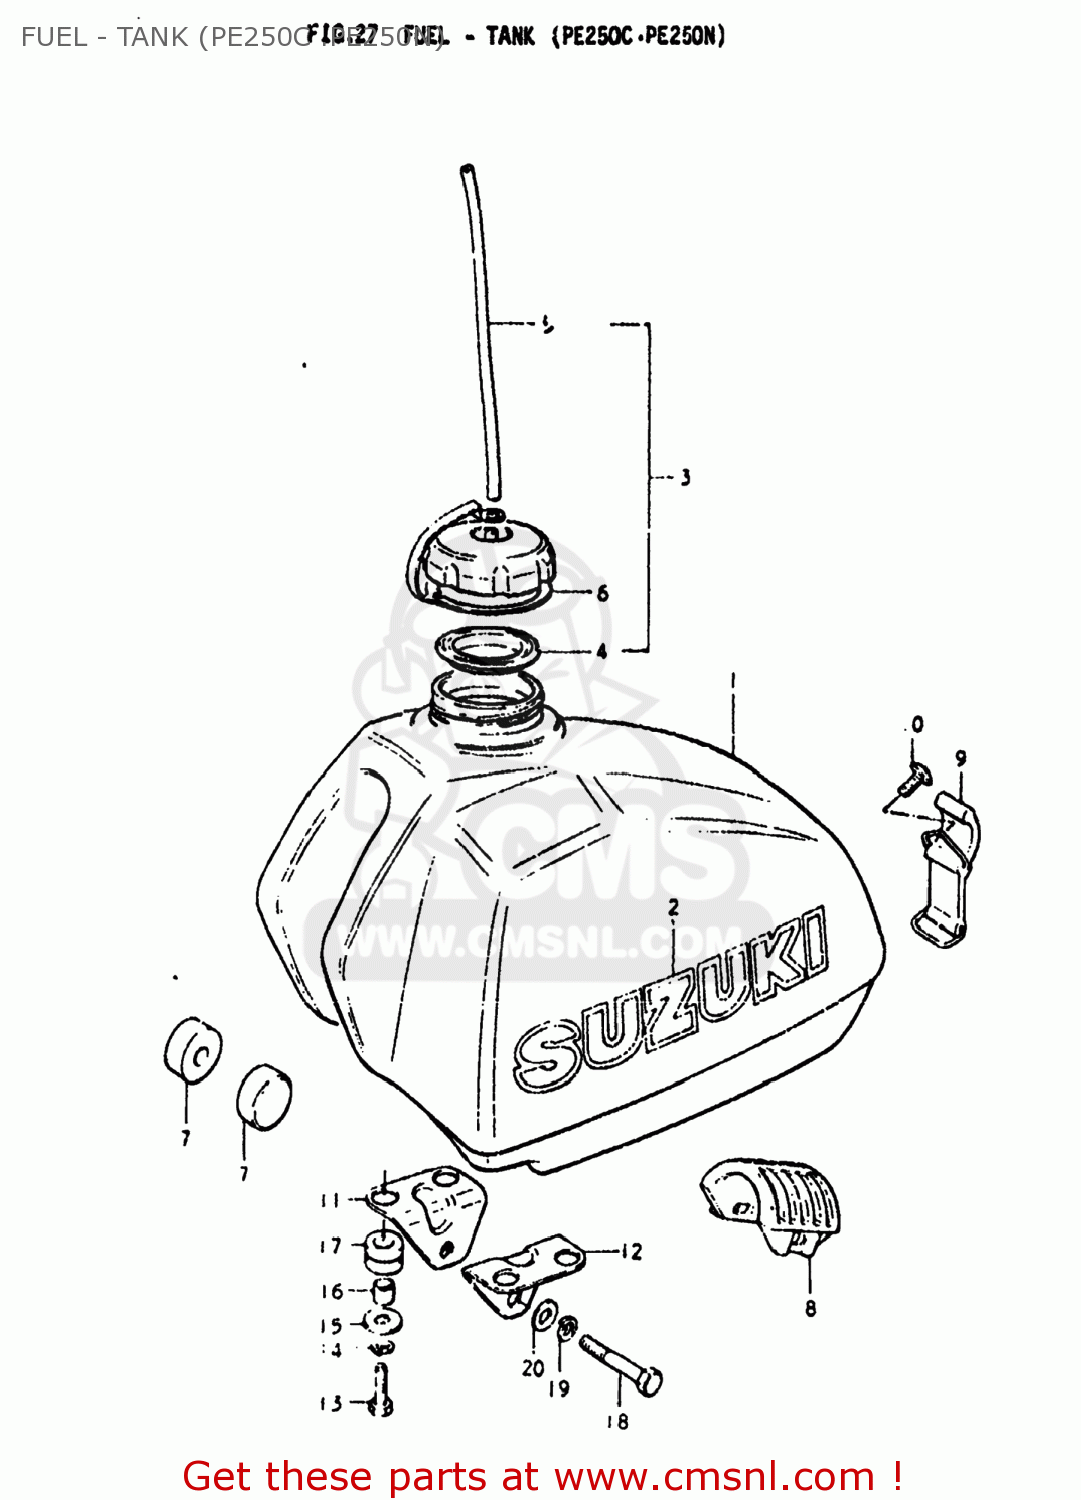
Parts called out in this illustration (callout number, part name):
1	TANK ASSEMBLY,FUEL
2	EMBLEM(BLACK)
3	CAP ASSY,FUEL TANK
4	GASKET,FUEL TANK CAP (NAS)
5	HOSE
6	BAND,FUEL TANK CAP
7	CUSHION
8	CUSHION,FUEL TANK
9	BAND
10	SCREW(6X18)
11	BRACKET,FUEL TANK
12	BRACKET,FUEL TANK
13	BOLT
14	LOCK WASHER
15	WASHER (6.5X20X1.2)
16	SPACER(6.8X12X11)
17	CUSHION
18	BOLT
19	LOCK WASHER
20	WASHER
